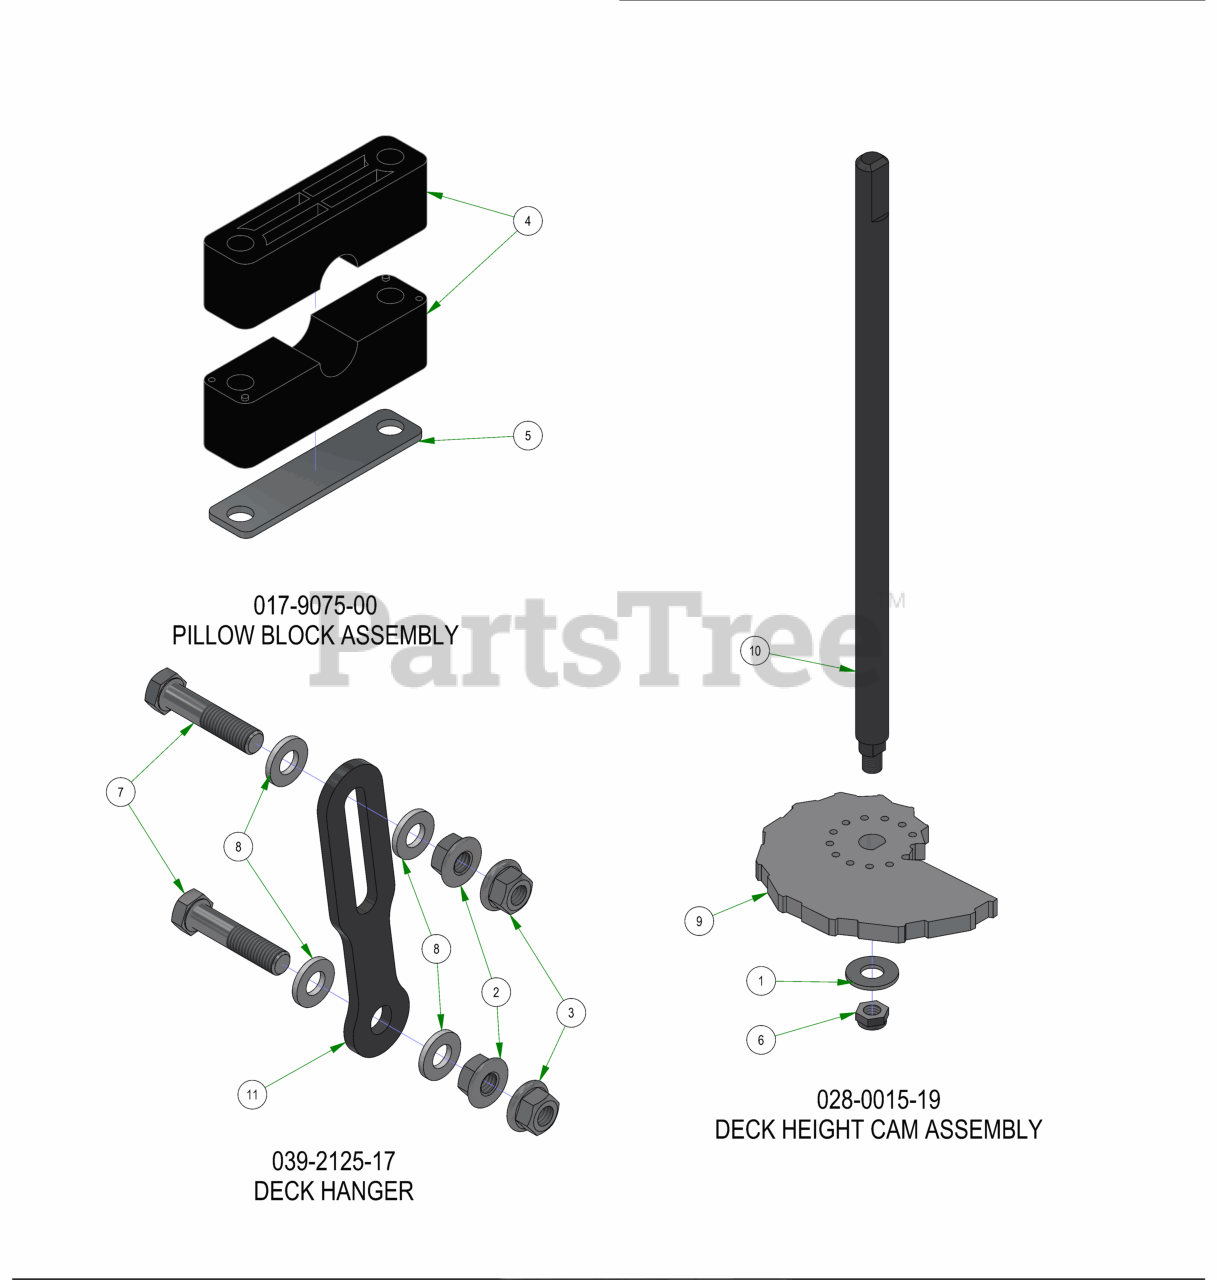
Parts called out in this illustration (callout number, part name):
1	3/8 FLAT WASHER USS (1" OD) ZINC
2	1/2-13 HEX SERRATED FLANGE NUT HARD/ZINC
3	1/2-13 NYLON INSERT FLANGE LOCKNUT ZINC
4	Two Piece Pillow Block
5	Two Piece Pillow Block Strap
6	3/8-24 Nylon Insert jam locknut
7	1/2-13 X 2-1/4 HEX CAP SCREW (GR.5) ZINC
8	.505 ID X 1.000 OD X .125 THICK FLAT WASHER NYLON
9	2019 Deck Height Cam
10	2019 Outlaw Gen2 Dial Rod
11	Deck Hanger
